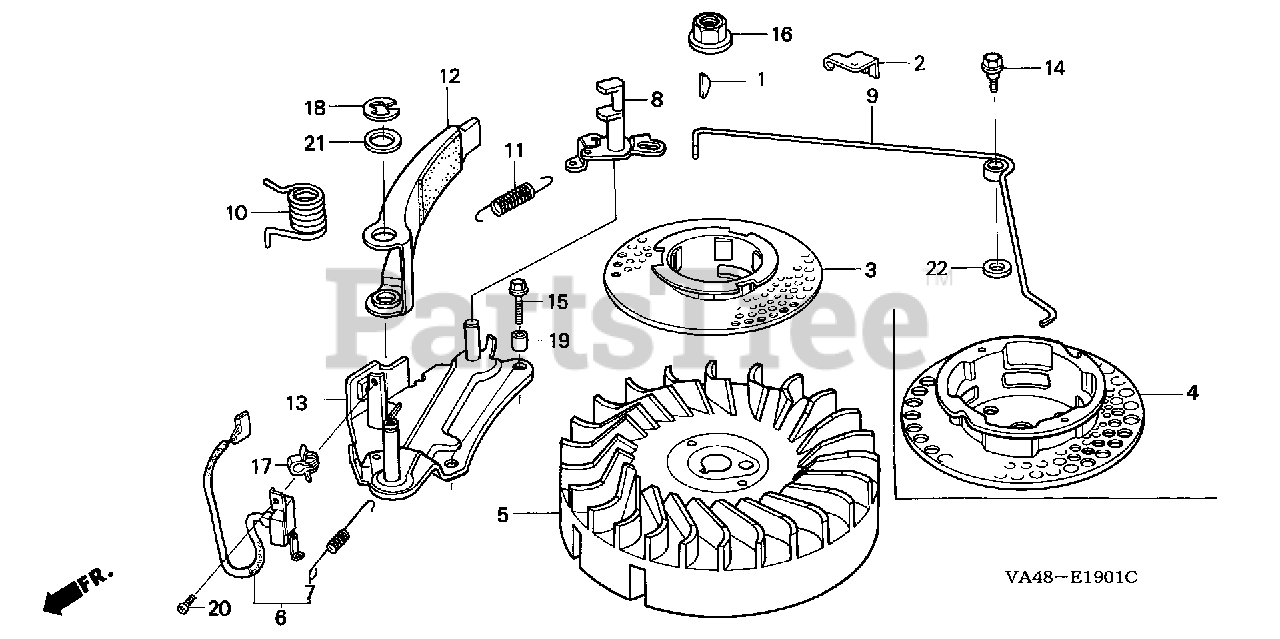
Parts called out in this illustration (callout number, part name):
1	KEY, SPECIAL WOODRUFF (25X18)
2	HOLDER, CABLE
3	PULLEY, STARTER
4	PULLEY, STARTER
5	FLYWHEEL
6	SWITCH ASSY., ENGINE STOP
7	SPRING, SWITCH CONTROL
8	CAM, BRAKE
9	ROD, THROTTLE RETURN
10	SPRING, BRAKE
11	SPRING, BRAKE RETURN
12	BRAKE
13	BASE, BRAKE
14	BOLT, FLANGE (6MM)
15	BOLT, FLANGE (6X22)
16	NUT, SPECIAL (14MM)
17	CLIP, WIRE HARNESS
18	E-RING (10MM)
19	PIN, DOWEL (8X9)
20	SCREW, PAN (4X8)
21	WASHER, PLAIN (12MM)
22	WASHER, DRUM STOPPER
